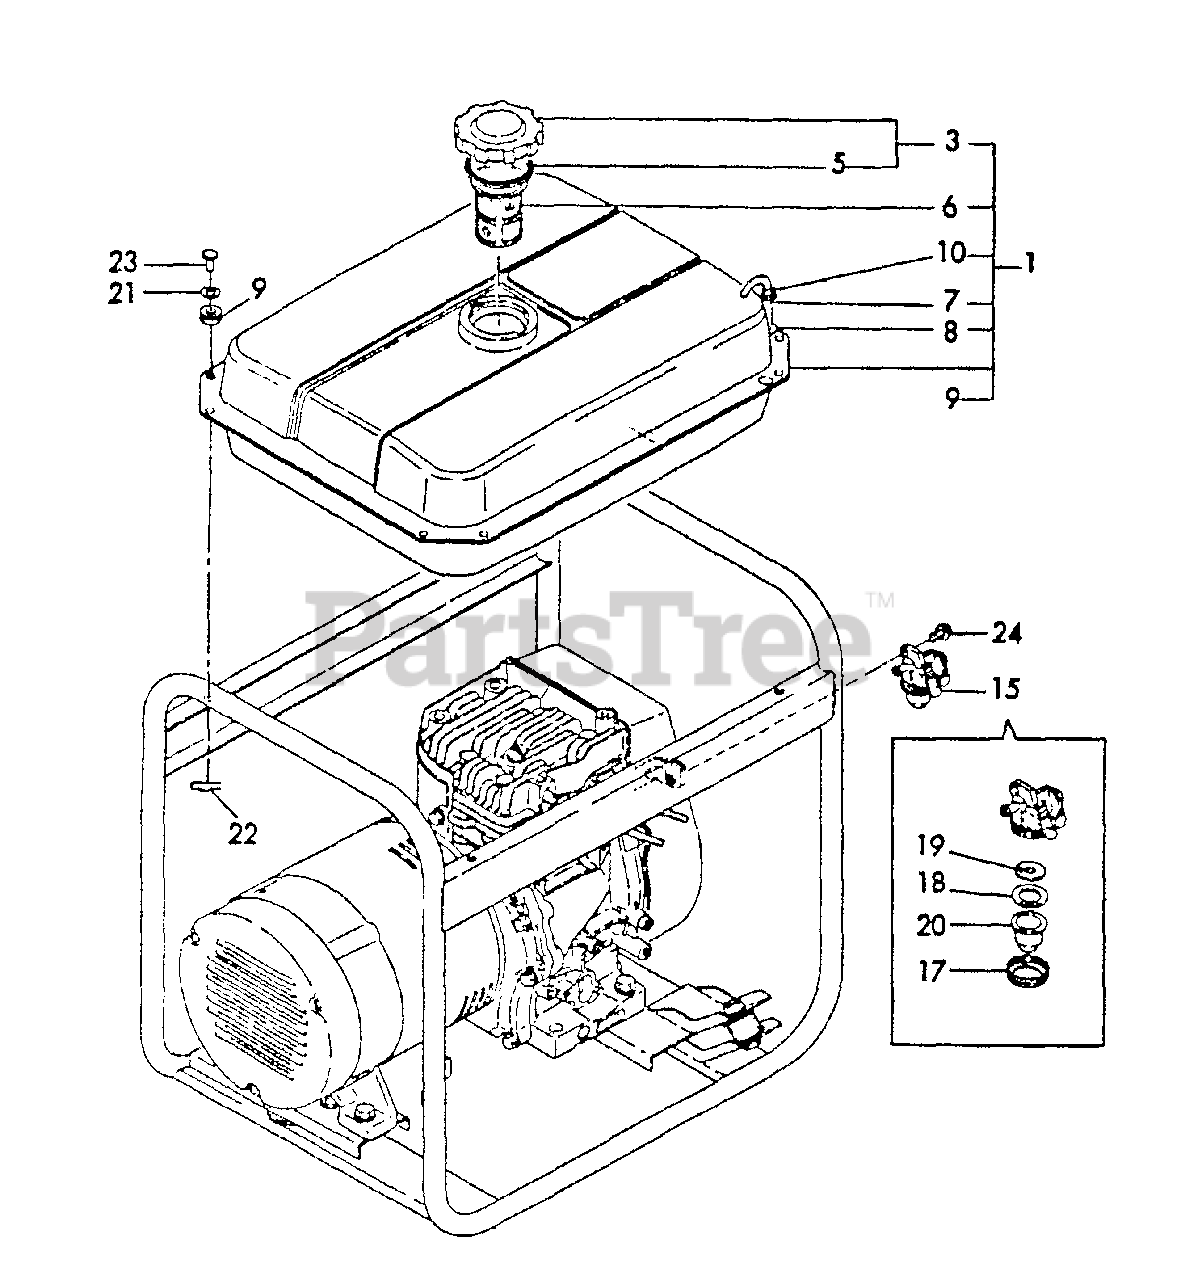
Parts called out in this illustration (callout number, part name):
1	TANK ASSY, FUEL
3	CAP ASSY
5	GASKET
6	STRAINER, FUEL
7	PIPE, GAUGE
8	GROMMET
9	GROMMET
10	CLAMP, HOSE - 9
15	COCK ASSY, FUEL
17	RETAINER
18	GASKET
19	FILTER, FUEL
20	BOWL, STRAINER
21	WASHER
22	PIN - 6 -- SNAP
23	PIN 6×14
24	BOLT - 6×8 -- PLATED
